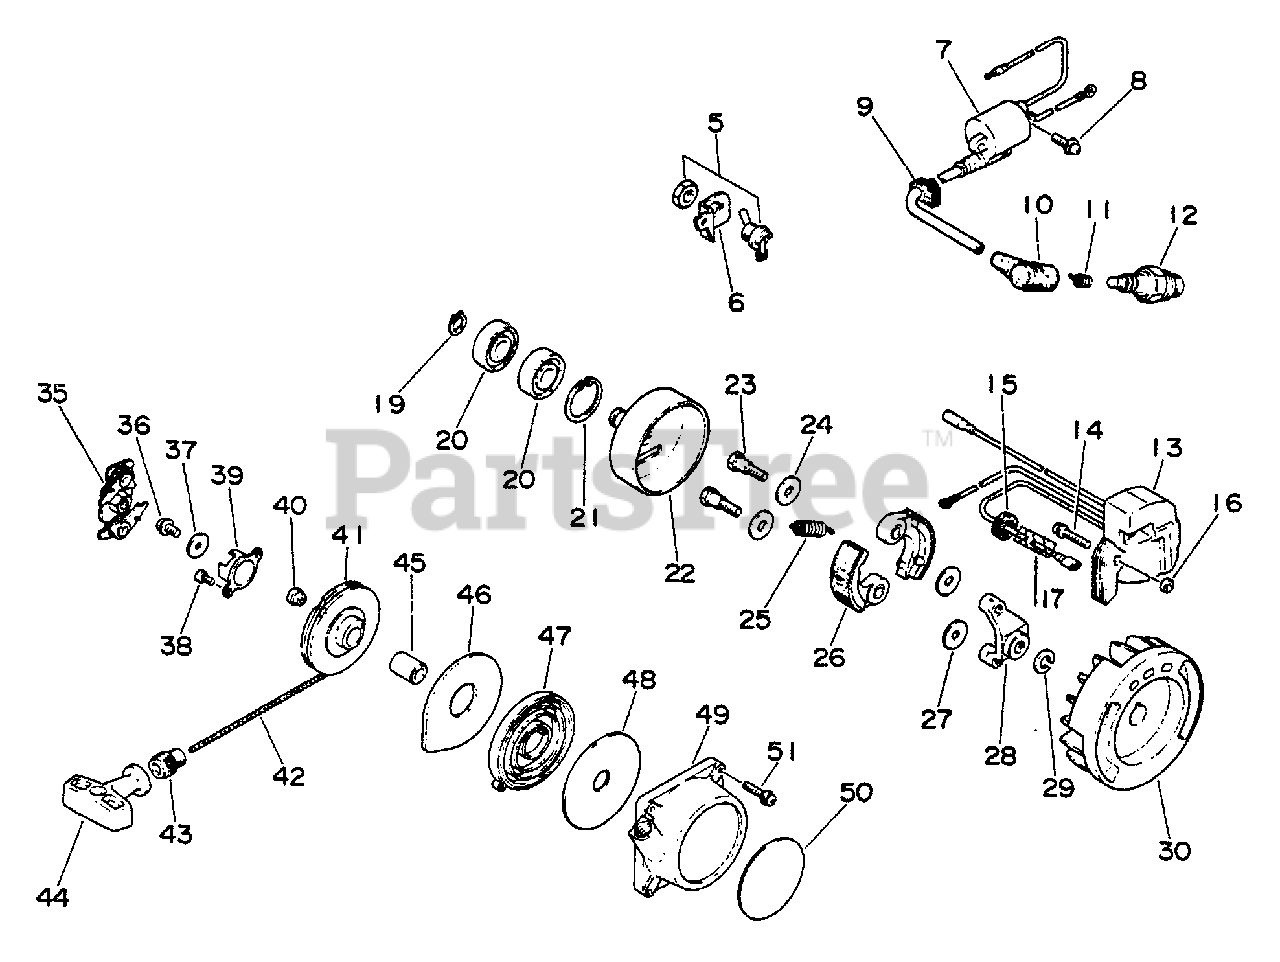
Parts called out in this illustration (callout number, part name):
5	SWITCH, IGNITION
6	BRACKET, SWITCH
7	COIL, IGNITION
8	SCREW 4×14
10	CAP, SPARK PLUG
11	TERMINAL, SPARK PLUG
12	SPARK PLUG - BM6A
13	COIL, IGNITION
14	SCREW 4×22
17	TUBE
19	RING, RETAINING - 12
20	BEARING, BALL
21	RING, SNAP Ø32
22	DRUM, CLUTCH
23	BOLT, CLUTCH
25	SPRING, CLUTCH
26	SHOE, CLUTCH
27	WASHER 6.2×19×1.0
28	BOSS, CLUTCH
29	WASHER, SPRING 8
30	FLYWHEEL
35	STARTER PAWL ASSY
36	SCREW 5×10
37	WASHER 5.2×16×1.0
38	SCREW 4×8
39	PAWL CATCHER
40	CLIP, STARTER ROPE
41	REEL, ROPE
42	ROPE, STARTER 3.5×850
43	GUIDE, ROPE
46	PLATE, SIDE
47	SPRING, RECOIL
48	PLATE, SIDE
49	CASE, STARTER
50	LABEL - ECHO
51	SCREW 4×20
